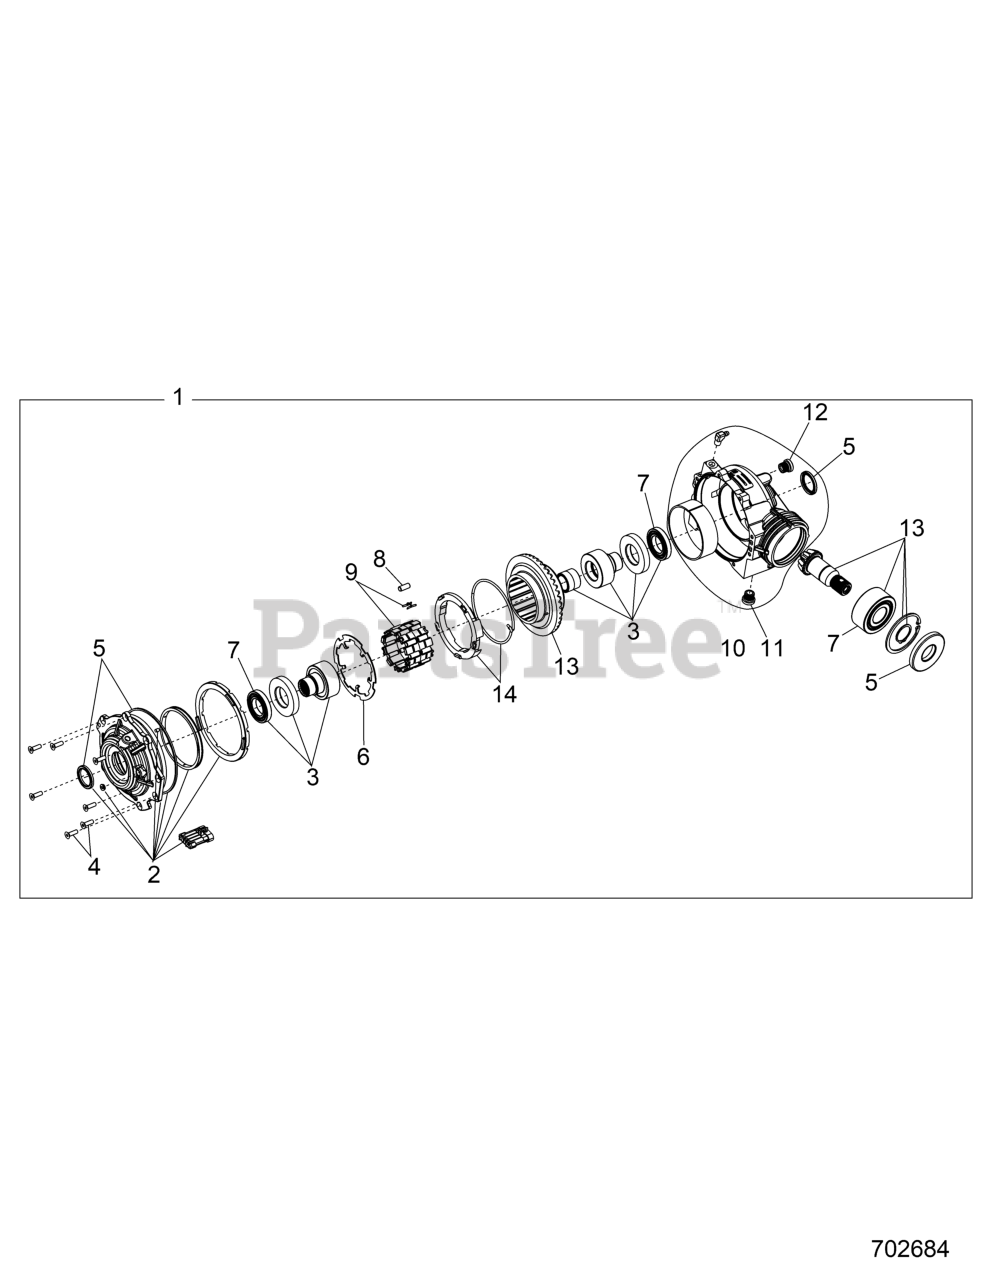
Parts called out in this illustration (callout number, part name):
1	ASM-GEARCASE,FRONT,5
2	ASM-COVER,OUTPUT
3	KIT-HUB,ASM
4	KIT-FASTENER
5	KIT-SEAL REPAIR
6	PLATE-4WD ARMATURE
7	BEARING-PINION,5306
8	K-CLUTCH ROLLS
9	ASSY, ROLL CAGE ZN
10	KIT, GEARCASE ASSY
11	DRAIN PLUG(6203-95-010)
12	FILL PLUG(1300-04-001-T)
13	ASM. GEAR HOUSING AND PINION GEAR
14	K-TORSION SPRING & RETAINER
